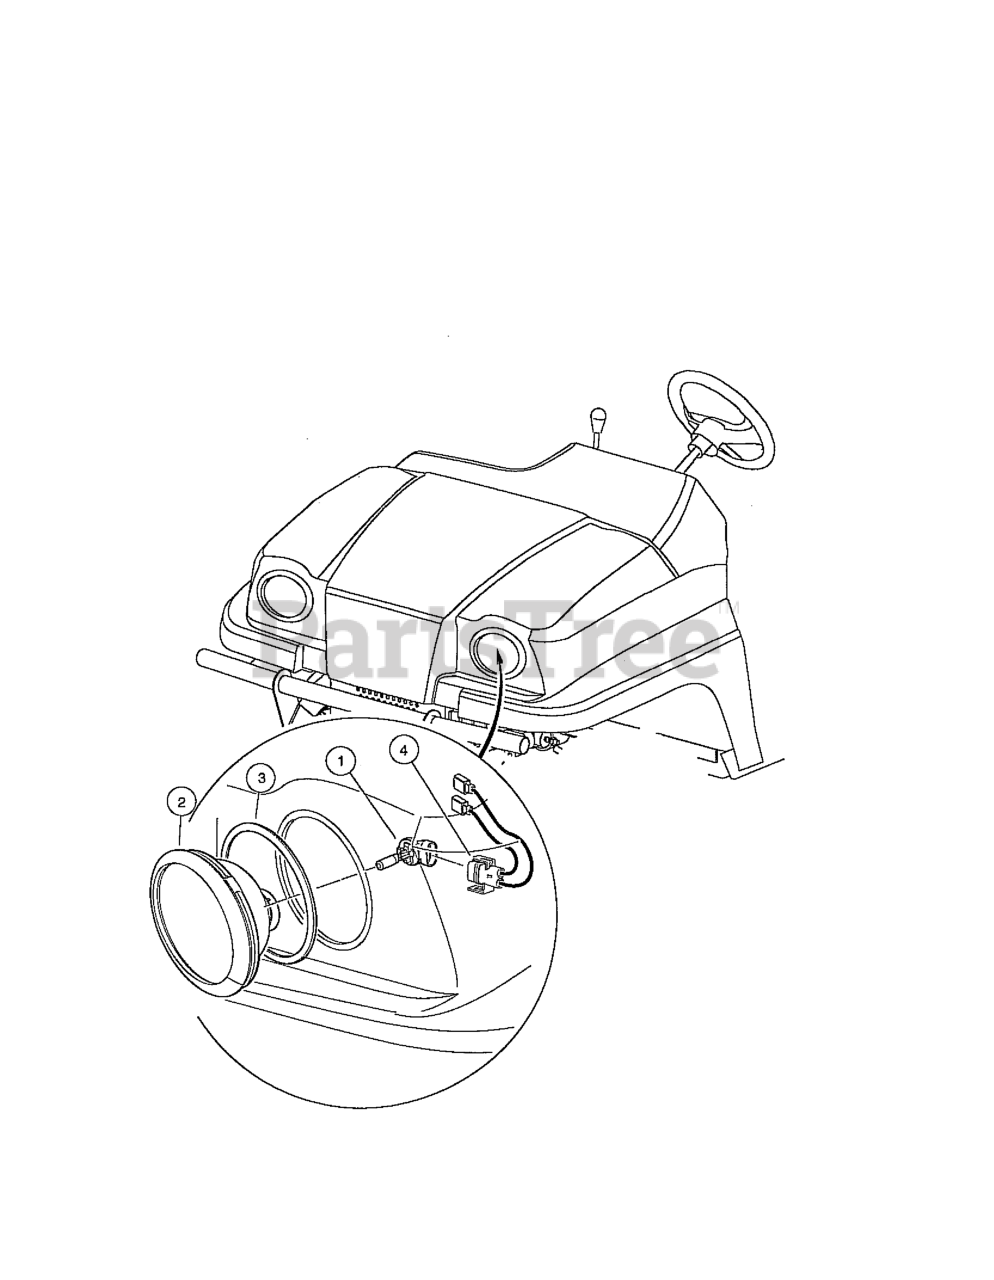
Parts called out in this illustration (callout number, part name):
1	HEADLIGHT ASSY, DRIVER
2	SPACER-HEADLIGHT-OVAL
3	HARNESS-HADLIGHT
